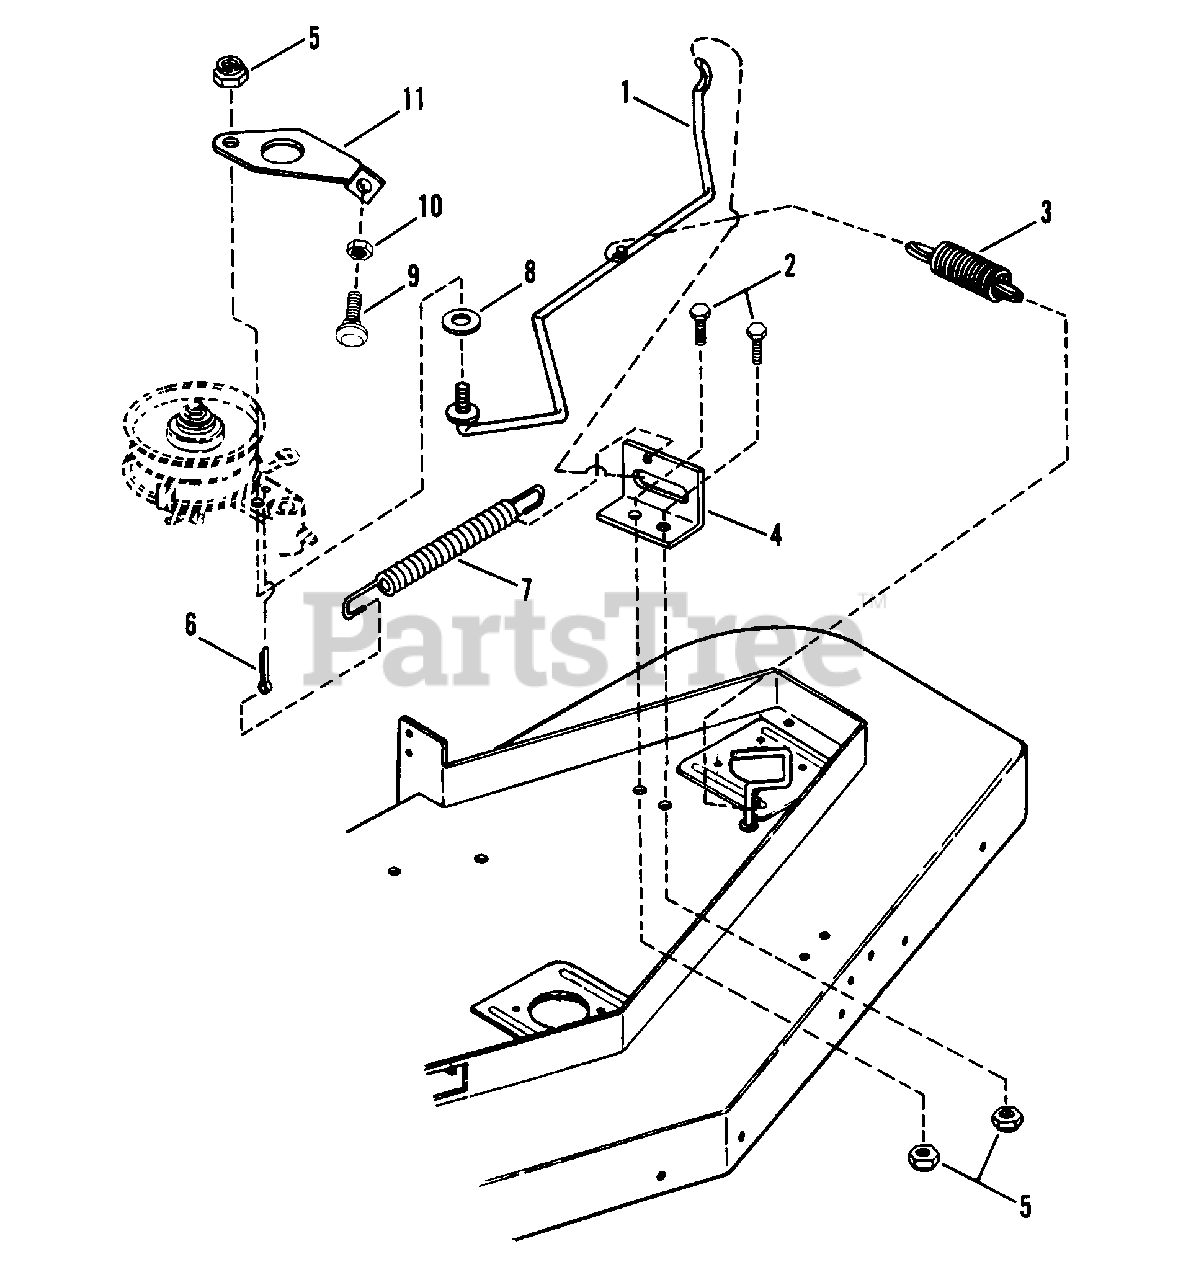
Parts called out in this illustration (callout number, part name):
1	GUIDE, Brake Belt
2	BOLT, 3/8-16 X 3/4" GD5 CZ
3	SPRING, Traction
4	BRACKET, Brake Arm
5	NUT, 3/8-16 HEX NYLON LOCK
6	COTTER-PIN, 3/16 x 3/4"
7	SPRING, Idler Return
8	WASHER, 3/8 Wave
9	BOLT, 5/16-18 x 1 3/4" Carriage, Grade 2
10	NUT, 5/16-18 Hex Jam
11	ARM, Brake, 48" Deck
